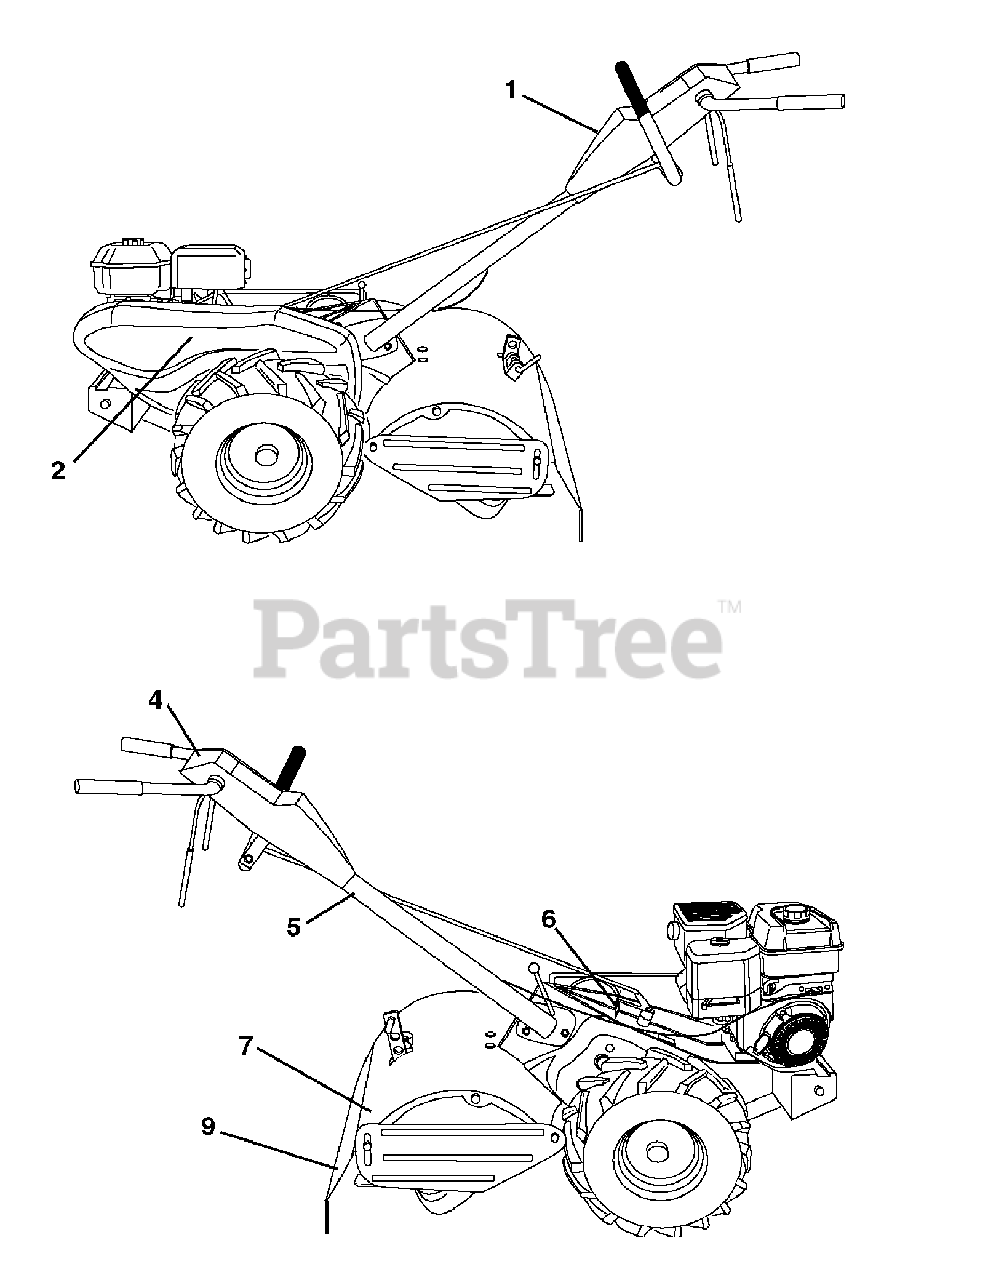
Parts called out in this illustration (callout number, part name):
4	DECAL.CNTRL.PNL.OPER.ENG/FR
5	DECAL TI
6	DECAL.SHIFT.INDICATOR.TILLER
7	DECAL WARNING
